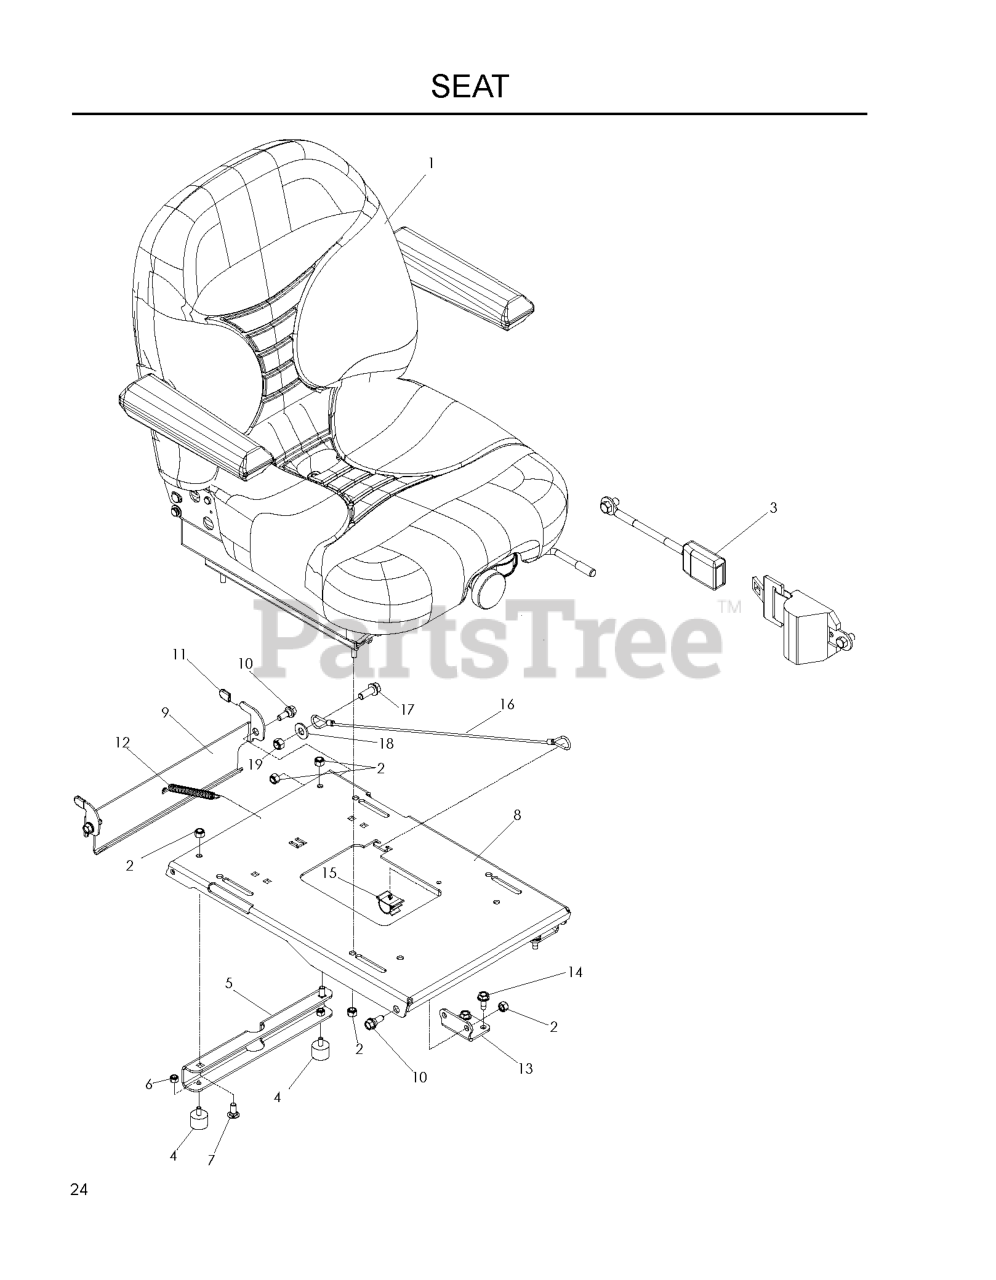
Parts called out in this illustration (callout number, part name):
1	SEAT - SUSP, NC SWITCH
2	NUT 5/16 NYLOC
3	SEAT BELT, RETRACTABLE
4	STUD/PLATE MOUNT
5	STANDOFF, SEAT PAN
6	NUT.1/4-20.HEX.NYLOC.ZD
7	BOLT 5/16C X 3/4" CARRIAGE
8	PAN, SEAT - BLACK
9	LATCH, SEAT - BLACK
10	SB 5/16-18 HEX HD GD5, BLK ZN
11	GRIP, VINYL, .09 X .495 X.75
13	PIVOT, SEAT PAN
14	BOLT 5/16-18 X 3/4
15	PUSH-MOUNT WIRE CLIP
16	SEAT LANYARD
17	4CS 3/8C X 1 SERRATED HEAD
18	WASHER 3/8 FLAT
19	NUT 3/8-16 NYLOC
